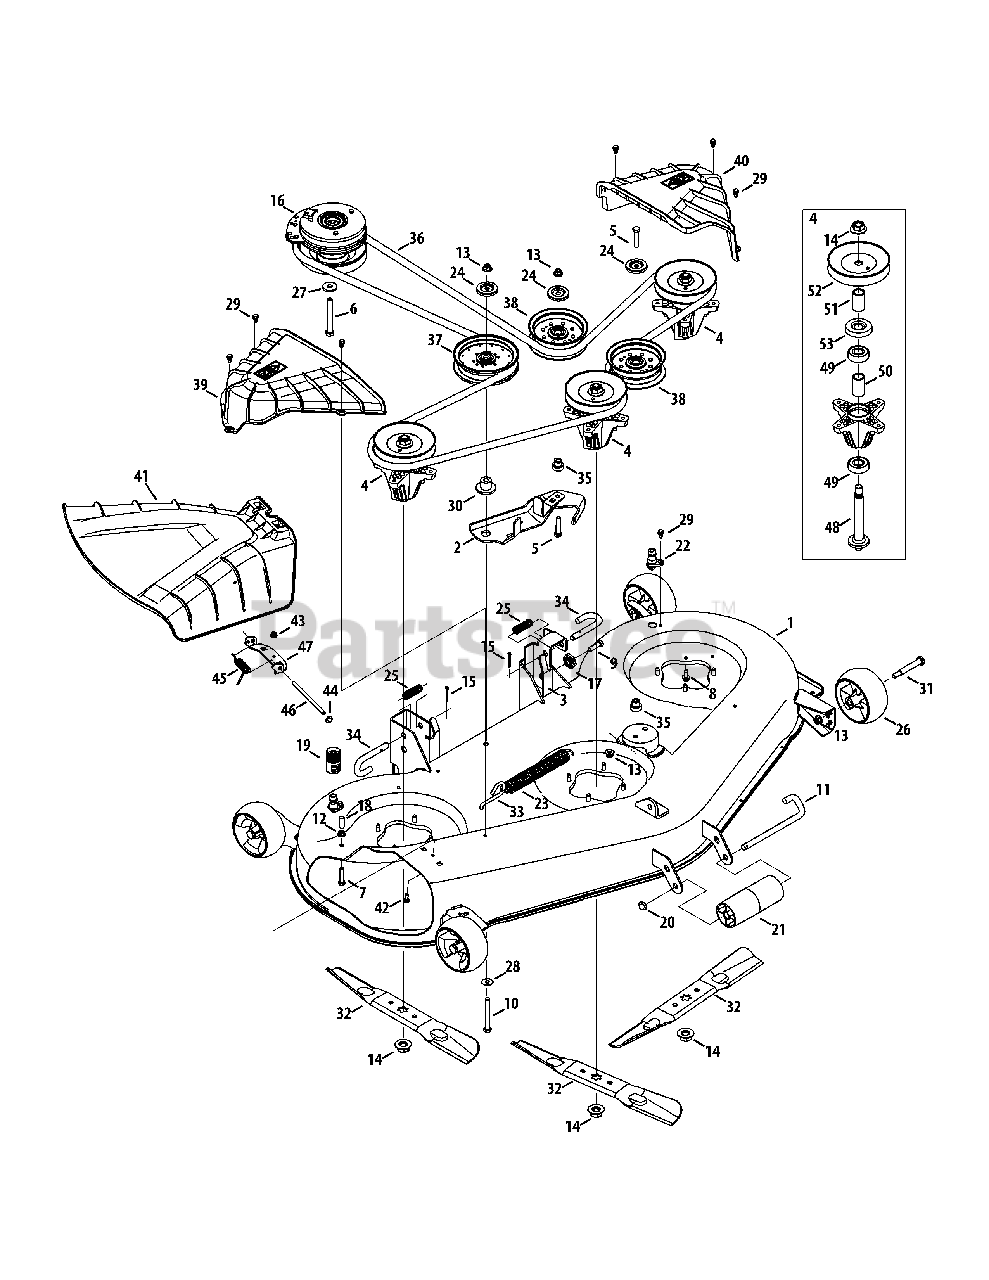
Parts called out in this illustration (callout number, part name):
1	54" Deck
2	Deck Idler Assembly
3	Deck Lift Bracket
4	Spindle Assembly
5	Hex Cap Screw, 3/8-16 x 1.75
6	Hex Cap Screw, 7/16-20 x 3.50
7	Hex Head Screw, 5/16-18 x 1.50
8	Hex Washer Screw, 5/16-18 x .750
9	Hex Flange Screw, 3/8-16
10	Hex Bolt 3/8-16 x 3.25"
11	Roller Pin, 1/2 x 7.31 Lg
12	Flange Lock Nut, 5/16-18
13	Flange Lock Nut, 3/8-16
14	HEX NUT
15	Cotter Pin, 5/32 x 1.25
16	Clutch, Electric PTO
17	Deck Adjustment Gear
18	Vinyl Cap, .29 x 1.00
19	Water Nozzle Adapter
20	Push Cap, 1/2
21	Front Roller
22	Deck Wash Nozzle
23	Extension Spring, 1.25 OD x 1.751
24	Pulley Cap
25	Compression Spring, .66 x 1.9
26	Deck Ball Wheel, 5.0
27	Flat Washer, .450 x 1.25 x .164
28	Flat Washer, .385 x 1.0 x .030
29	Shoulder Screw, 1/4-20 x 0.50
30	Shoulder Spacer
31	Shoulder Screw, .5 x 2.5 x 3/8-16
32	Blade, 18.67
33	Deck Spring Rod
34	Deck Hanger Rod
35	Shoulder Spacer
37	Idler Pulley, 5.00 Dia.
38	Pulley, Idler, 4.50" Dia.
39	Belt Cover, RH
40	Belt Cover, LH
41	Chute Deflector Assembly
42	SCREW 1/4-20 x .620 GR5
43	Nut, Flange Lock, 1/4-20, Nylon
44	PUSH CAP
45	Spring, Torsion, .440 ID x 1.75
46	Hinge Pin
48	Spindle Shaft, 6.11 Long
49	Ball Bearing
50	Spacer, .792 x 1.060 x 1.860
51	Spacer, .792 x 1.060 x 1.782
52	Deck Pulley
53	Bearing Shield
